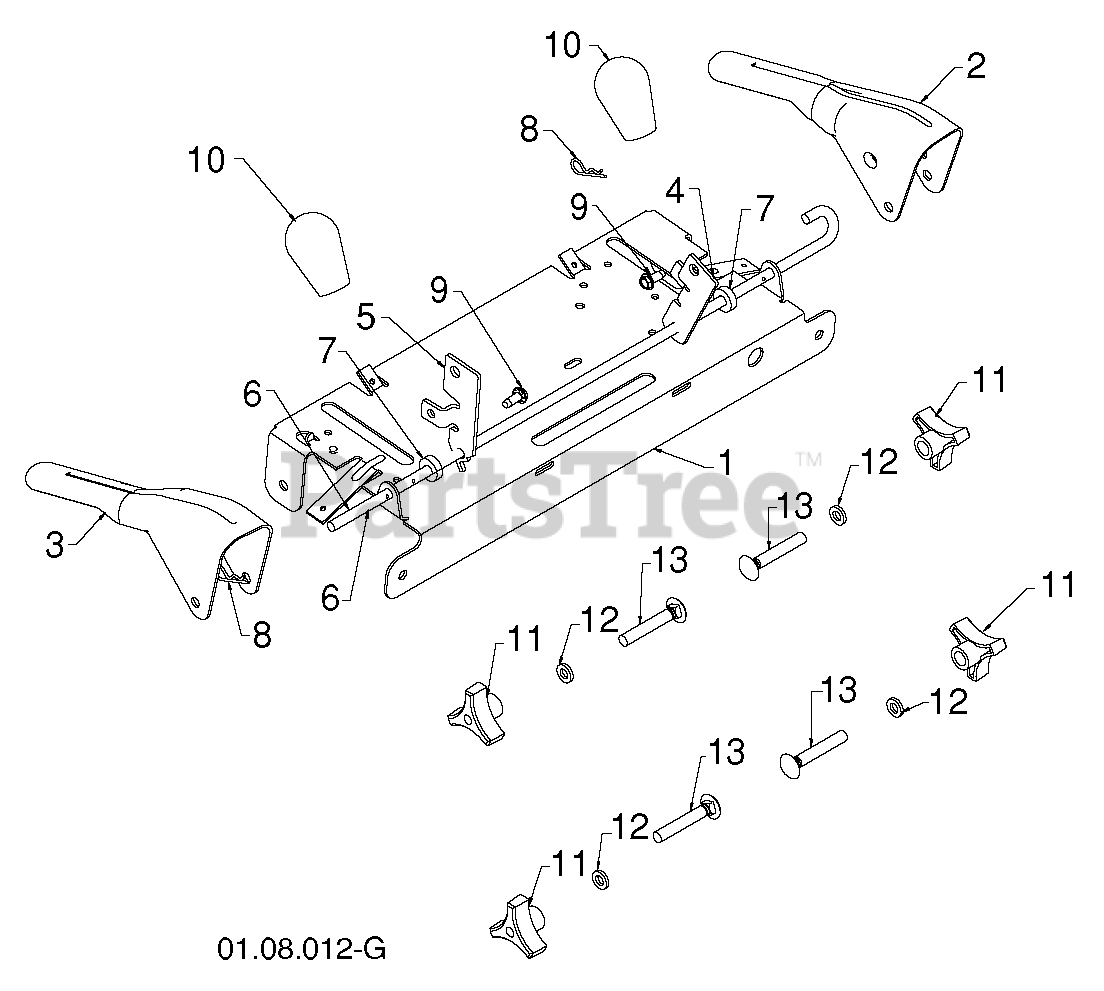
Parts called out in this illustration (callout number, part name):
1	PANEL.CONTROL.PNT.BLA
2	LEVER.CONTROL.LH.BLACK
3	LEVER.CONTROL.RH.GREY
4	ARM.TRACTION.ROD.YZ
5	ARM.IMPELLER.ROD.SNOW
6	BAIL.CONTROL.INTERLOCK
7	SPACER.CONTROL.LEVER
8	RETAINER
9	SCREW 14-20 X 5/8
10	KNOB.OVERMOLD.DS.HUSQVARNA/BLK
11	KNOB.HANDLE.3/8.TRI-POINT.BLAC
12	WASHER
13	BOLT 3/8-16 X 2-1/4
